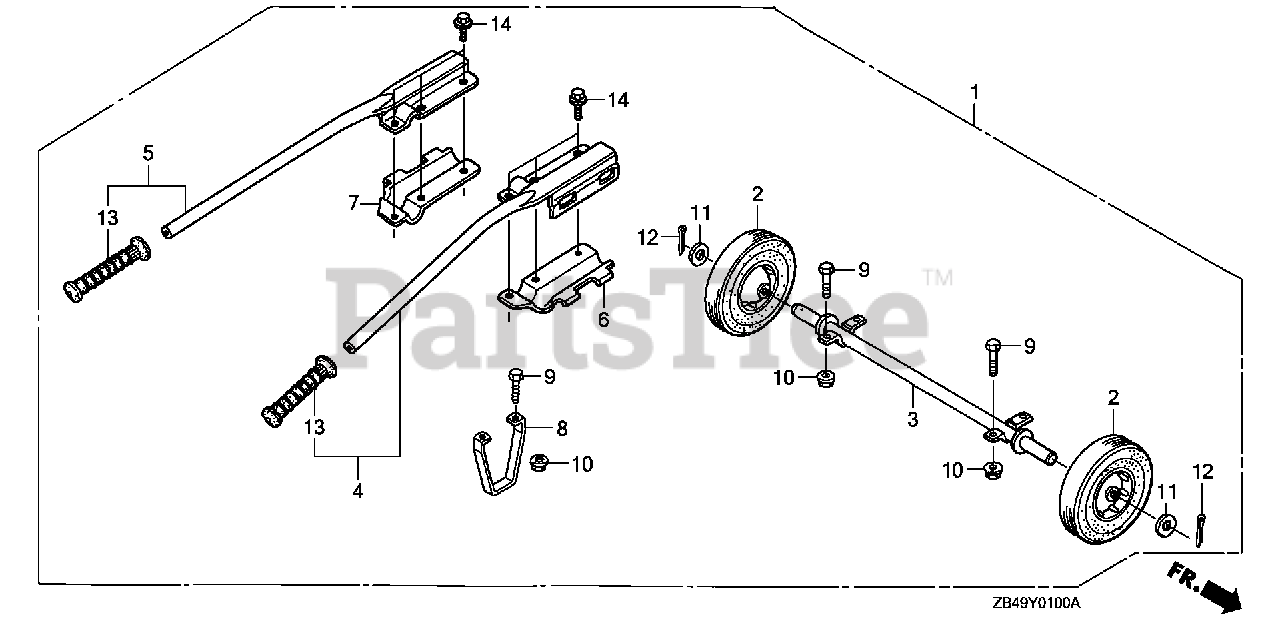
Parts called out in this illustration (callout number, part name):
1	WHEEL KIT (2-WHEELS)
2	WHEEL (GLEASON 10"X2.75"=254X70)
3	SHAFT, WHEEL
4	HANDLE, R. (LOWER)
5	HANDLE, L. (LOWER)
6	BRACKET, R. HANDLE (UPPER)
7	BRACKET, L. HANDLE (UPPER)
8	STAND
9	BOLT, HEX. (8X16)
10	NUT, FLANGE (8MM)
11	WASHER, PLAIN (20MM)
12	PIN, SPLIT (4.0X28)
12	PIN, SPLIT (4.0X30)
13	GRIP D, R. HANDLE
14	BOLT, FLANGE (8X16)
